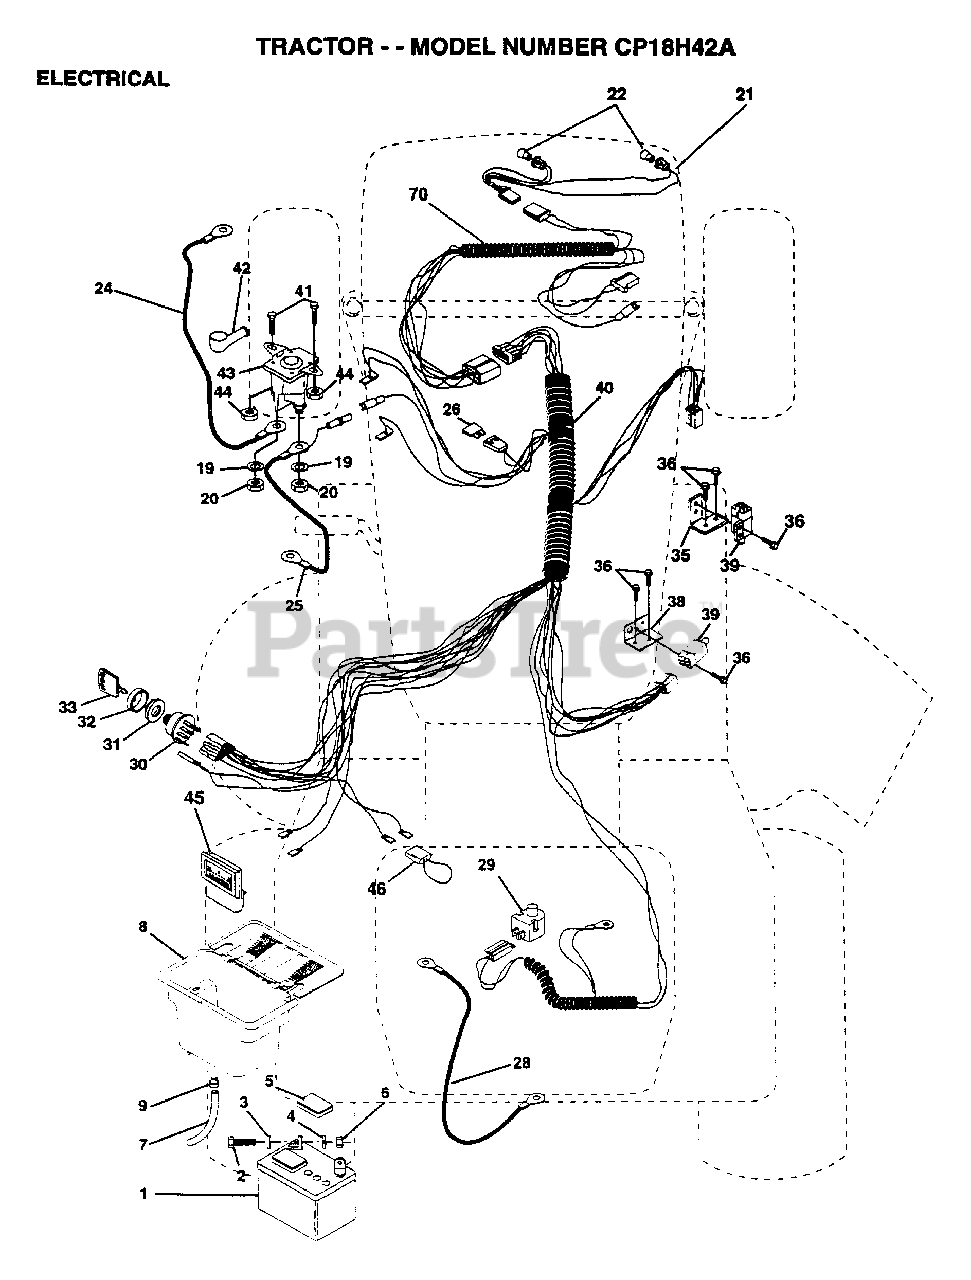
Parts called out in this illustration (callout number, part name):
2	BOLT LT
3	WASHER
4	LOCKWASHER
5	"CAP,BATTERY "
7	TUBE T
9	HOSE CLAMP T
20	NUT
21	"HARNESS,LIGHT SOC"
22	HEADLAMP BULB
24	CABLE-BATTERY T
25	CABLE.BTRY.6GA.RD
26	FUSE HYT
28	CABLE T
29	SWITCH SEAT
30	SWITCH IGN 4POS
31	NUT IGNITION
32	COVER KEY SWITCH
33	KEY
35	BRACKET LT
36	SCREW
38	BRACKET SWITCH IN
39	SWITCH INTERLOCKT
41	BOLT.HX.1/4-20
44	NUT
46	PROTECTION LOOP
70	HARNESS.ENG.LT.
